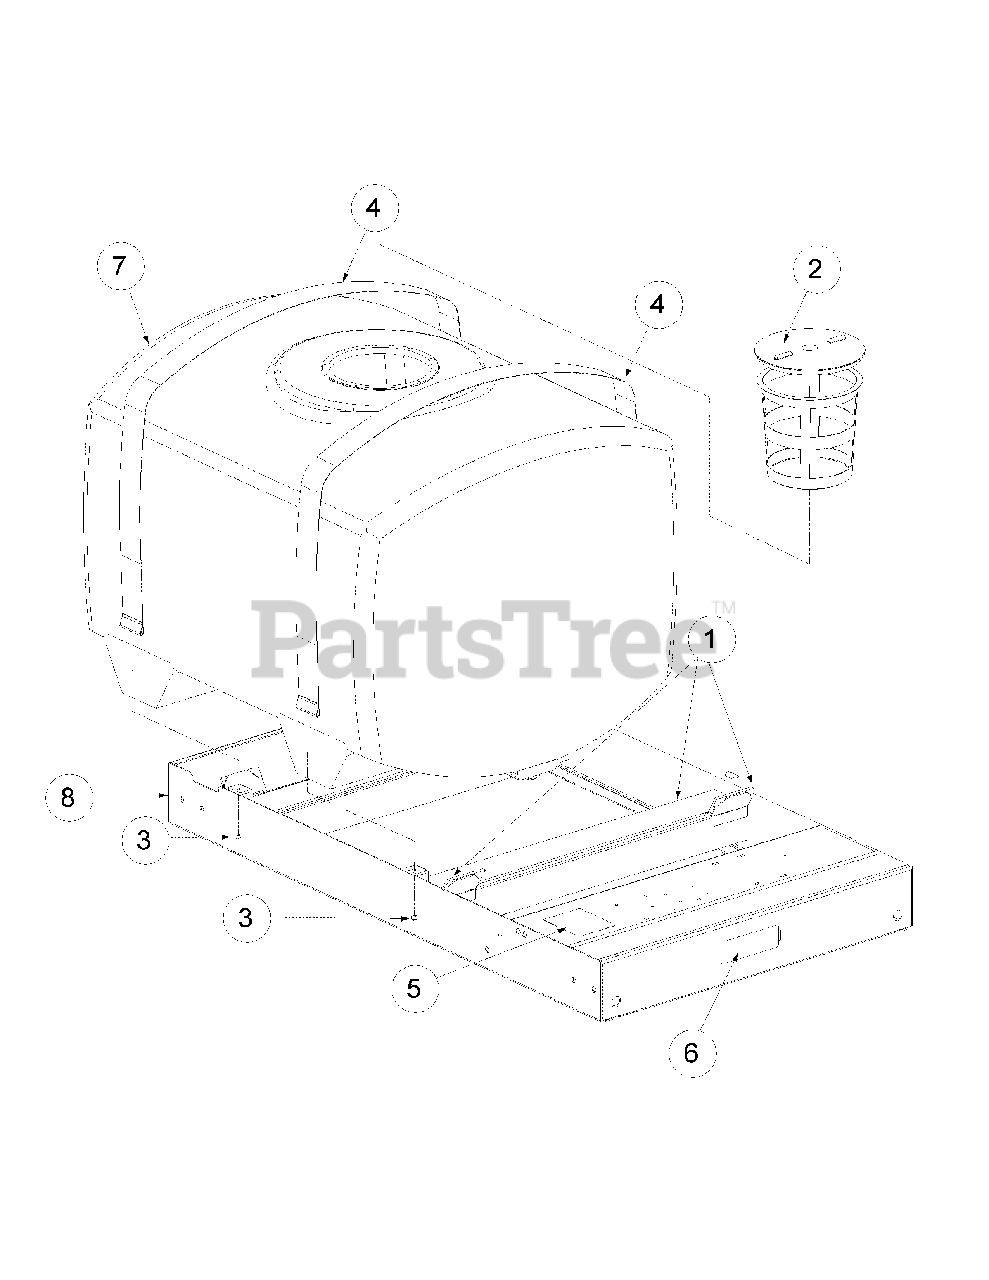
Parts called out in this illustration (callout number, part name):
1	Foam, Adhesive Backed, 4'' x 1/4'' by ft.
2	Tank, Lid
3	Nut, Nylock 5/16 - 18
4	Tank Strap Assembly
5	Decal Safety Procedures
6	Decal, CCC, 2-3/8" x 7-1/8"
7	200 Gallon Tank Assembly
8	Main Frame Assembly
